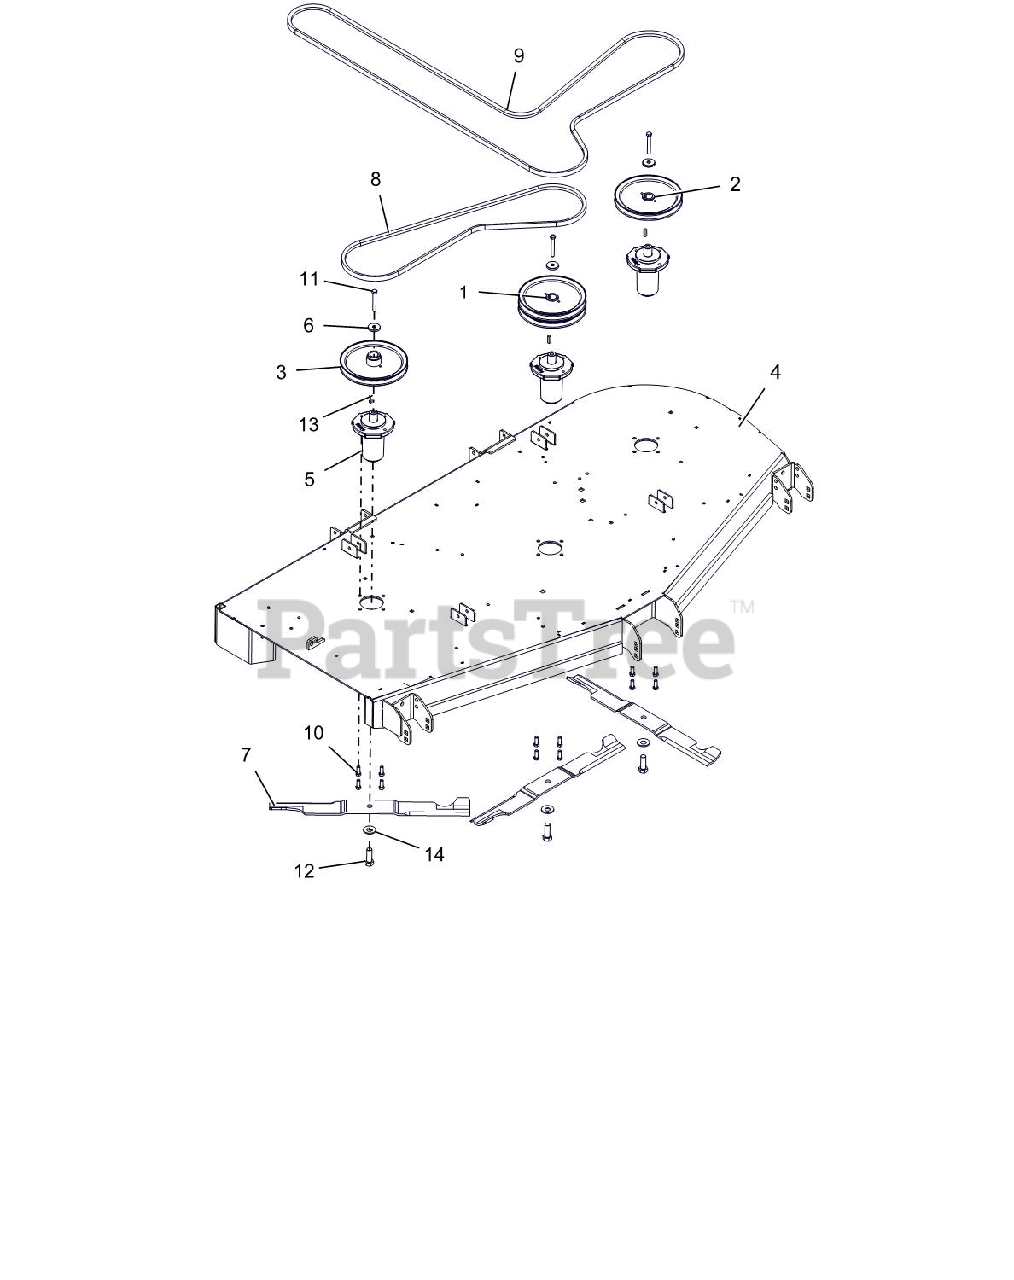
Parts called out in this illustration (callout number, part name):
1	SHEAVE-DOUBLE 1.00"IDX8.25"OD
2	SHEAVE-SINGLE 1.00"IDX8.25"OD
3	SHV-SINGLE 1.00"ID X 8.25"OD
4	72"SIDE DISCH DECK WMT W/SAFE
5	ASM, MAINT FREE SPINDLE
6	RETAINER, SHEAVE
7	BLADE, 72"
8	V-BELT, B-COGGED
9	V-BELT, HB WRAPPED
10	BLT-HEX .38-16X1.0 GR8 YZ EP30
11	BLT-HEX .38-16X2.75 GR8 YWZC
12	BLT-HEX .62-18X1.75 GR8 YWZC
13	KEY, SQ .25X.25X1.00 RC 40-50
14	WSHR-BLVL .669X1.535X.138
